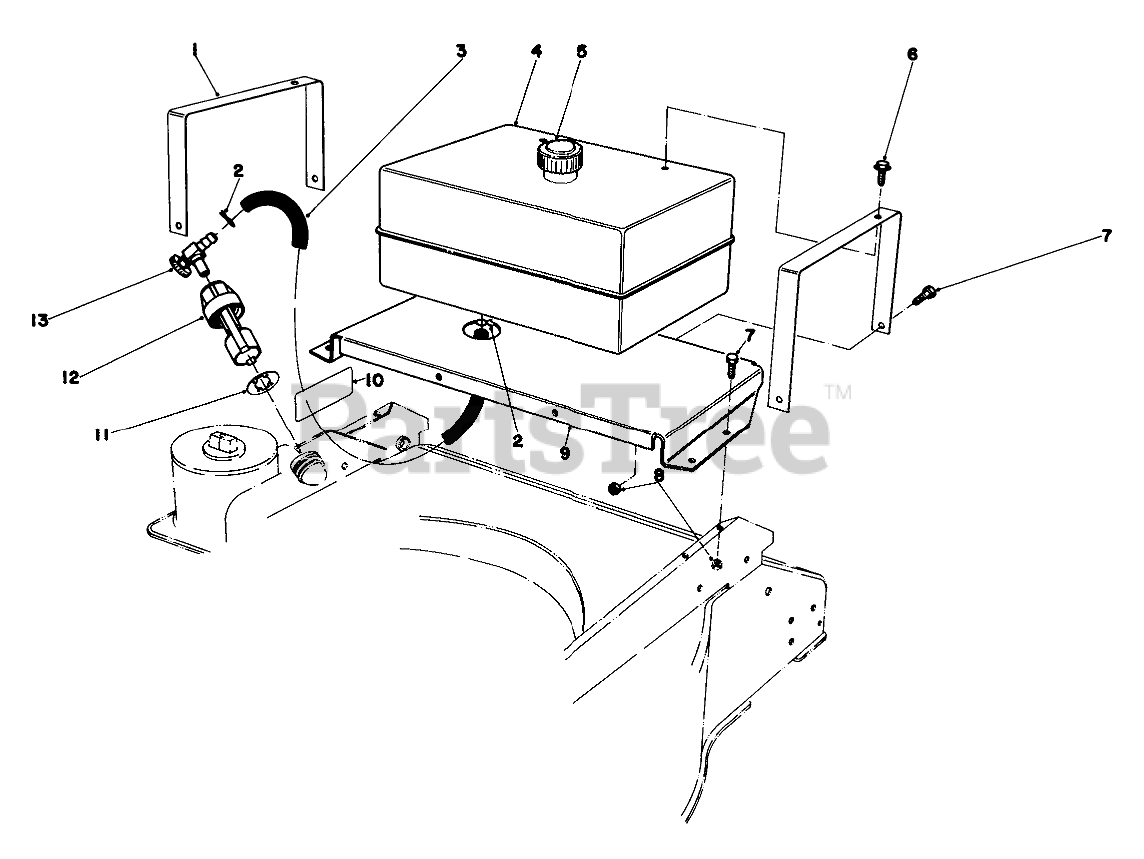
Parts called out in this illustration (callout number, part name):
1	Tank Strap
2	Clamp
3	Fuel Line
4	Fuel Tank
6	SCREW-HWH
7	SCREW-HH
8	NUT-LOCK, CONE
9	Fuel Tank Mtg. Bracket
10	Decal-Caution
11	GASKET
12	Fuel Control Valve (Incl. Ref. #11)
13	.125 ID SHUTOFF VALVE
